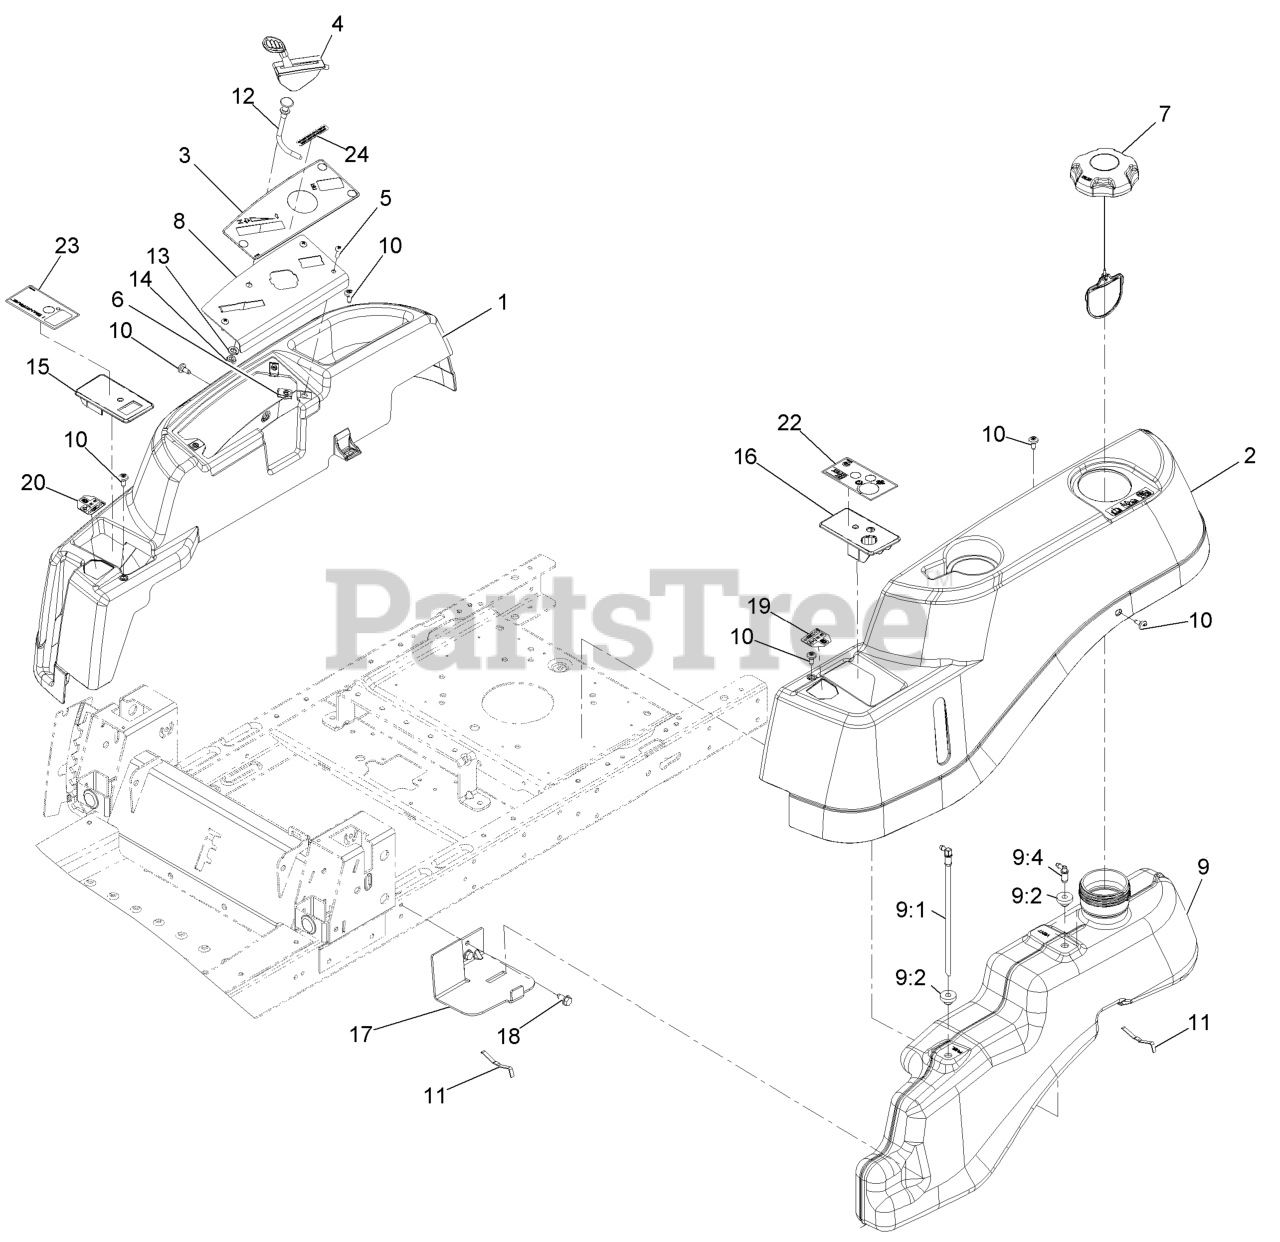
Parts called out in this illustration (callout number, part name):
3	DECAL-PANEL, CONTROL
4	CABLE-THROTTLE
5	SCREW-PRH
6	Nut-Retainer-Panel 1/4-20
8	PLATE-CONTROL
9	FUEL TANK ASM
9:1	CONNECTOR-ELBOW, 90 DEG
9:2	BUSHING
9:4	FITTING-PLASTIC
10	SCREW-SHOULDER
11	SPRING
12	CABLE-CHOKE
13	WASHER-LOCK
14	NUT-HJ
15	COVER-RH
16	COVER-LH
17	SUPPORT-TANK, FRONT
18	Screw-HWH 5/16-18 X 3/4 Tf
19	DECAL-NMIR
20	DECAL-CONTROL, PEDAL
22	DECAL-KEYCHOICE
23	DECAL-BRAKE, PARKING
24	DECAL-SHUTDOWN
